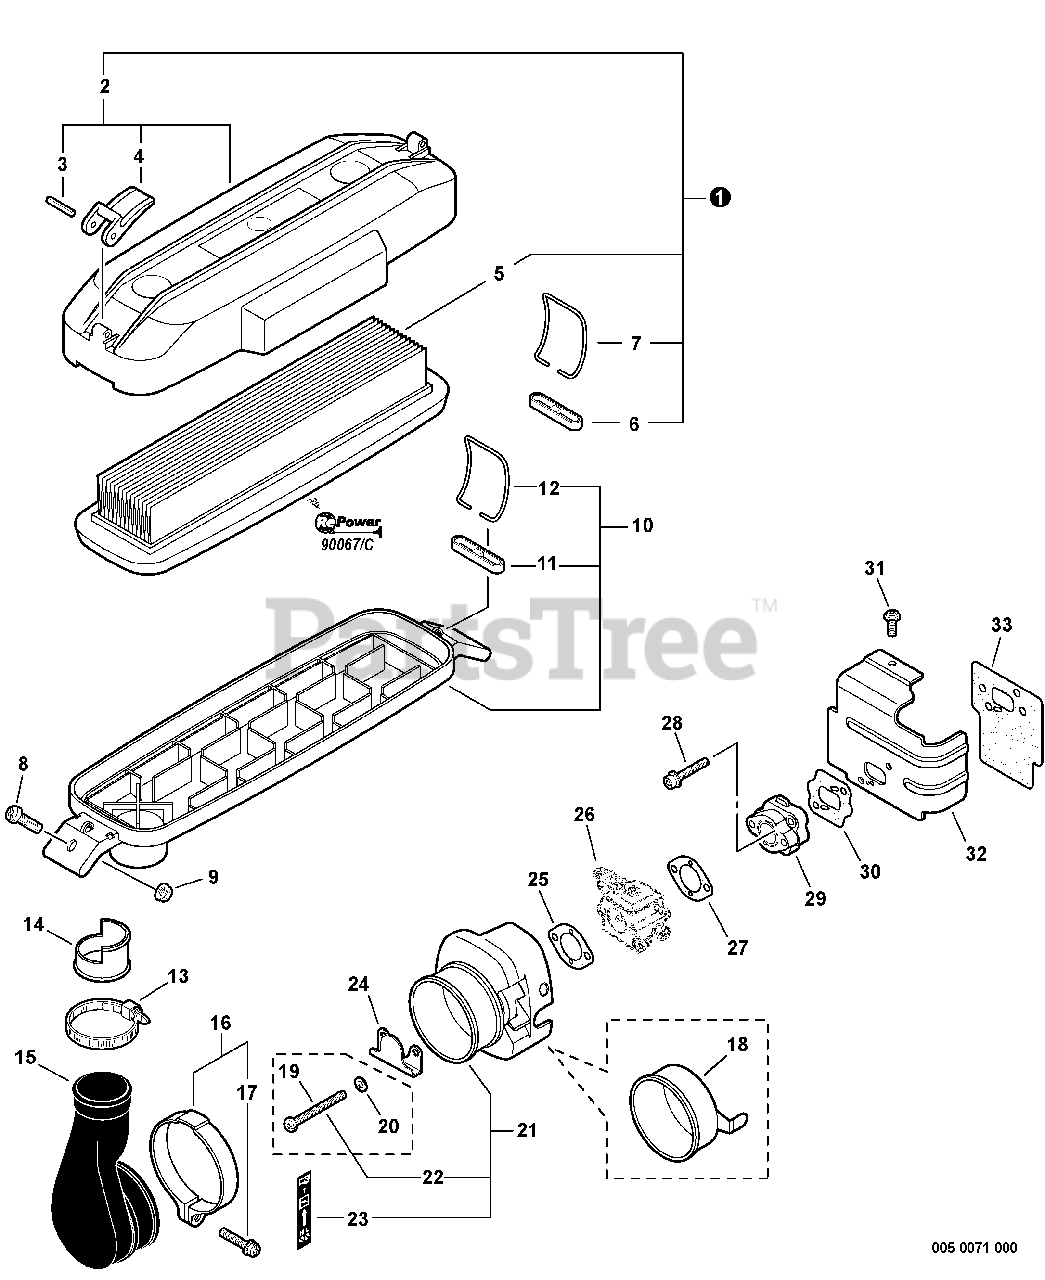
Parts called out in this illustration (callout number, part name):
1	AIR FILTER KIT
2	AIR FILTER COVER ASSY
3	PIN - SPRING -- 3X25
5	FILTER, AIR
6	RETAINER
7	RING, RETAINING
8	SCREW - 5X14
9	NUT - 5 -- FLANGE
10	AIR FILTER CASE ASSY
11	RETAINER
12	RING, RETAINING
13	CLAMP, HOSE
15	ADAPTOR, INTAKE
16	CLAMP KIT
17	SCREW - 5X25
18	BRACKET, AIR CLEANER - METAL
19	SCREW - 5X55
20	WASHER - 6
21	BRACKET KIT - PLASTIC
22	SCREW - 5X57
23	LABEL - CHOKE
24	PLATE, PREVENT
25	GASKET, INTAKE
26	CARBURETOR
27	GASKET, INTAKE
28	SCREW - 5X25
29	INSULATOR, INTAKE
30	GASKET, INTAKE
31	SCREW - 5X10
31	RePower TUNE-UP KIT
32	COVER, CYLINDER - INTAKE
33	SHIELD, INTAKE
34	RePower TUNE-UP KIT
